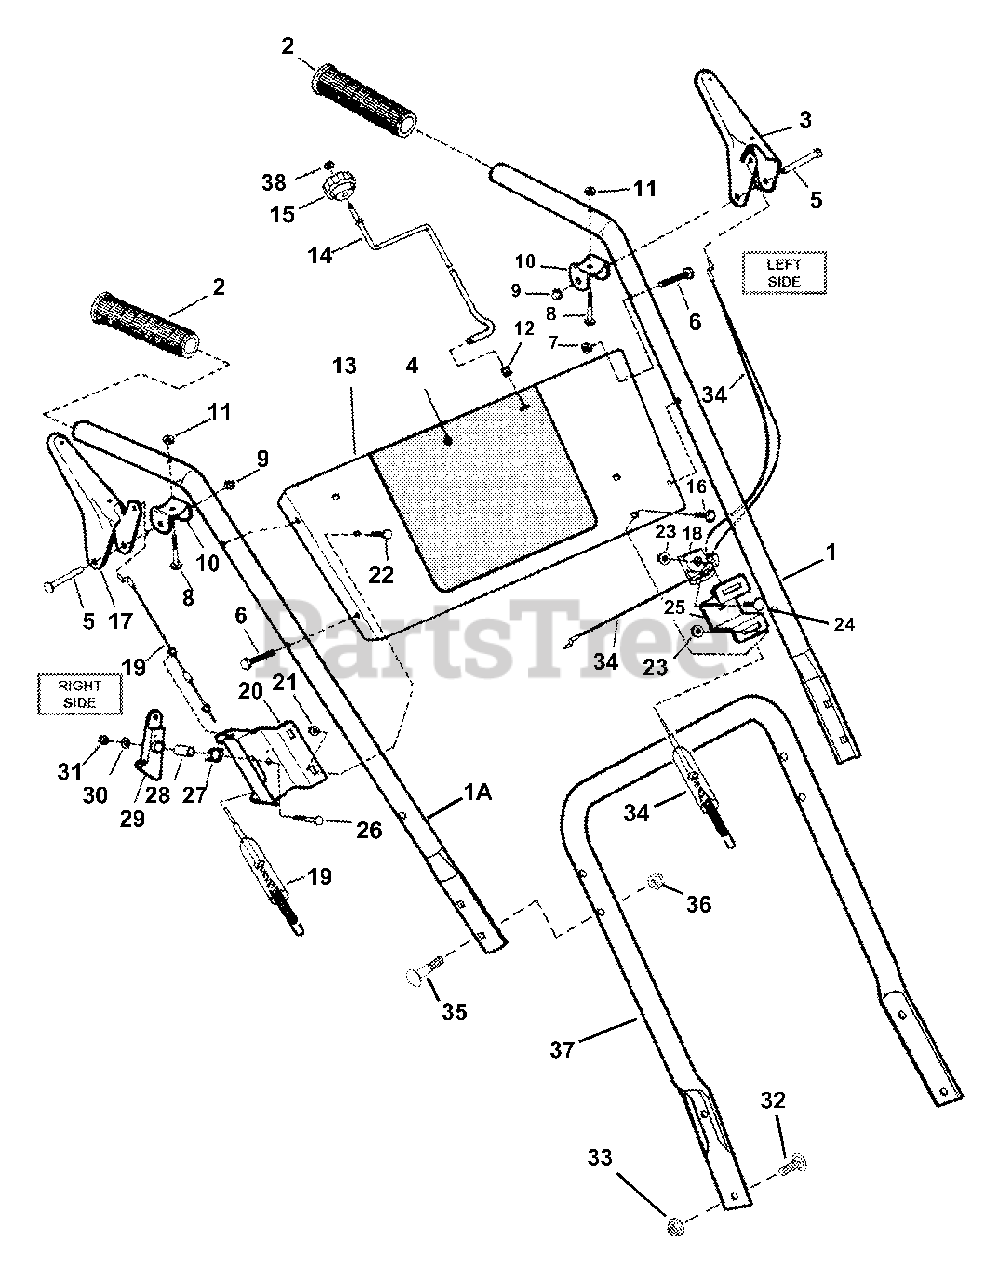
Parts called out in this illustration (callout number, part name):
1	BAR, Handle (Left Hand)
1A	BAR, Handle (Right Hand)
2	GRIP, Handle
3	HANDLE (Left Hand)
4	DECAL, Control Model 7/24
5	PIN, 1/4 x 1-7/8" Clevis
6	SCREW, 5/16-18 x 1-1/2" Hex Head Cap, Grade 5
7	NUT, 5/16-18 Hex Top Lock
8	SCREW, 1/4-28 x 1-3/8" Hex Head Cap, Grade 5
9	NUT, 1/4" Push
10	BRACKET, Handle
11	NUT, 1/4-28 Hex Top Lock
12	BUSHING
13	PANEL, Control
14	CRANK, Chute
15	KNOB, Chute Crank
16	BOLT, 1/4-20 x 1/2" Short Neck Carriage, Grade 5
17	HANDLE (Right Side)
18	GUIDE, Cable
19	CABLE, Auger Right Side
20	CAM BRACKET
21	NUT, #10-24 Hex Flange Lock
22	BOLT, #10-24 x 1/2" Flat Head Carriage
23	NUT, 1/4-20 Hex Flange Lock
24	BOLT, 1/4-20 x 3/4" Short Neck Carriage, Grade 5
25	BRACKET, Cable Guide Support
26	SCREW, 1/4-20 x 1" Hex Head Cap, Grade 5
27	SPRING, Cam Lock
28	SPACER
29	CAM LOCK
30	WASHER, 1/4" Flat
31	NUT, 1/4-20 Hex Center Lock
32	BOLT, 5/16-18 x 5/8" Short Neck Carriage, Grade 5
33	NUT, 5/16-18 Hex Flange Lock, Grade 5
34	CABLE, Clutch (Left Hand)
35	BOLT, 5/16-18 x 2" Square Neck Carriage, Grade 5
36	NUT, 5/16-18 Hex Nyloc
37	BAR, Handle (Lower)
38	NUT, 5/16-18 Hex Center Lock
